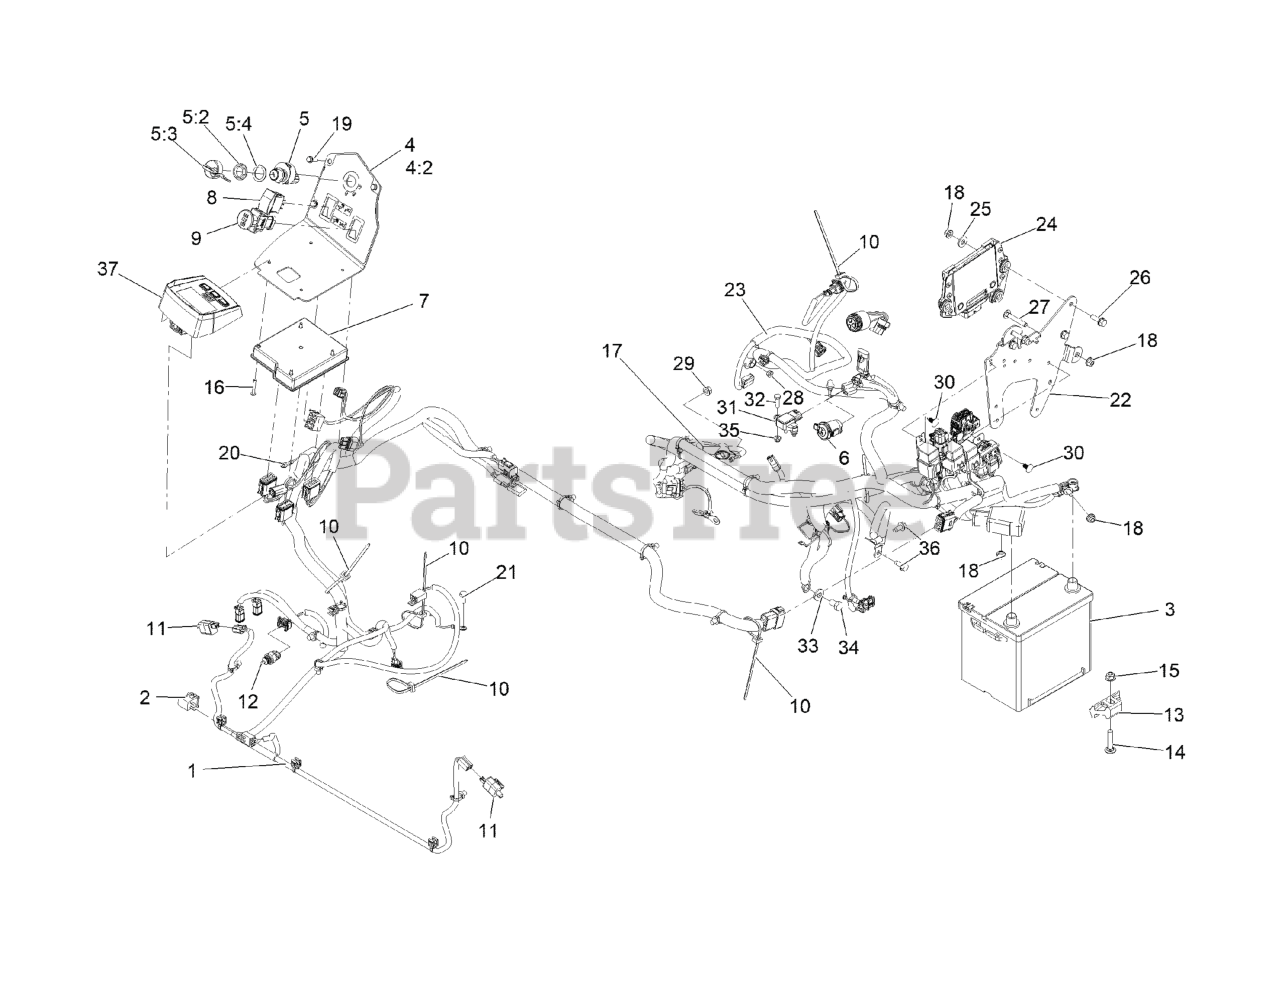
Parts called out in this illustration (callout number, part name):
1	HARNESS-WIRE
2	SWITCH-BAIL
3	Battery-Dry
4	Console ASM
4:2	DECAL-CONTROL PANEL
5	IGNITION SWITCH ASM
5:2	NUT-MOUNTING
5:3	IGNITION KEY SET
5:4	WASHER-BACKUP
6	PORT-POWER, 12V
7	Module-Mcu
9	SWITCH-PTO, SEALED
10	TIE-CABLE
12	SENSOR-TEMPERATURE
13	RETAINER-BATTERY
14	SCREW-CARR
15	NUT-HF, NI
16	SCREW-PPH
17	CABLE-BATTERY
18	NUT-HF, NI
19	SCREW-HWH
20	HARNESS-WIRE, JUMPER
21	BOLT
22	BRACKET-MOUNT, ECU
23	HARNESS-WIRE
24	ECU ASM-SERVICE
25	WASHER-FLAT
26	SCREW-HHF
27	BOLT-CARR
30	PLUG-PLASTIC
31	SENSOR-ATM
32	SCREW-HH
33	WASHER-BELLEVILLE
34	SCREW-HH
36	Screw-HWH 5/16-18 X 3/4 Tf
37	MODULE, LDU
